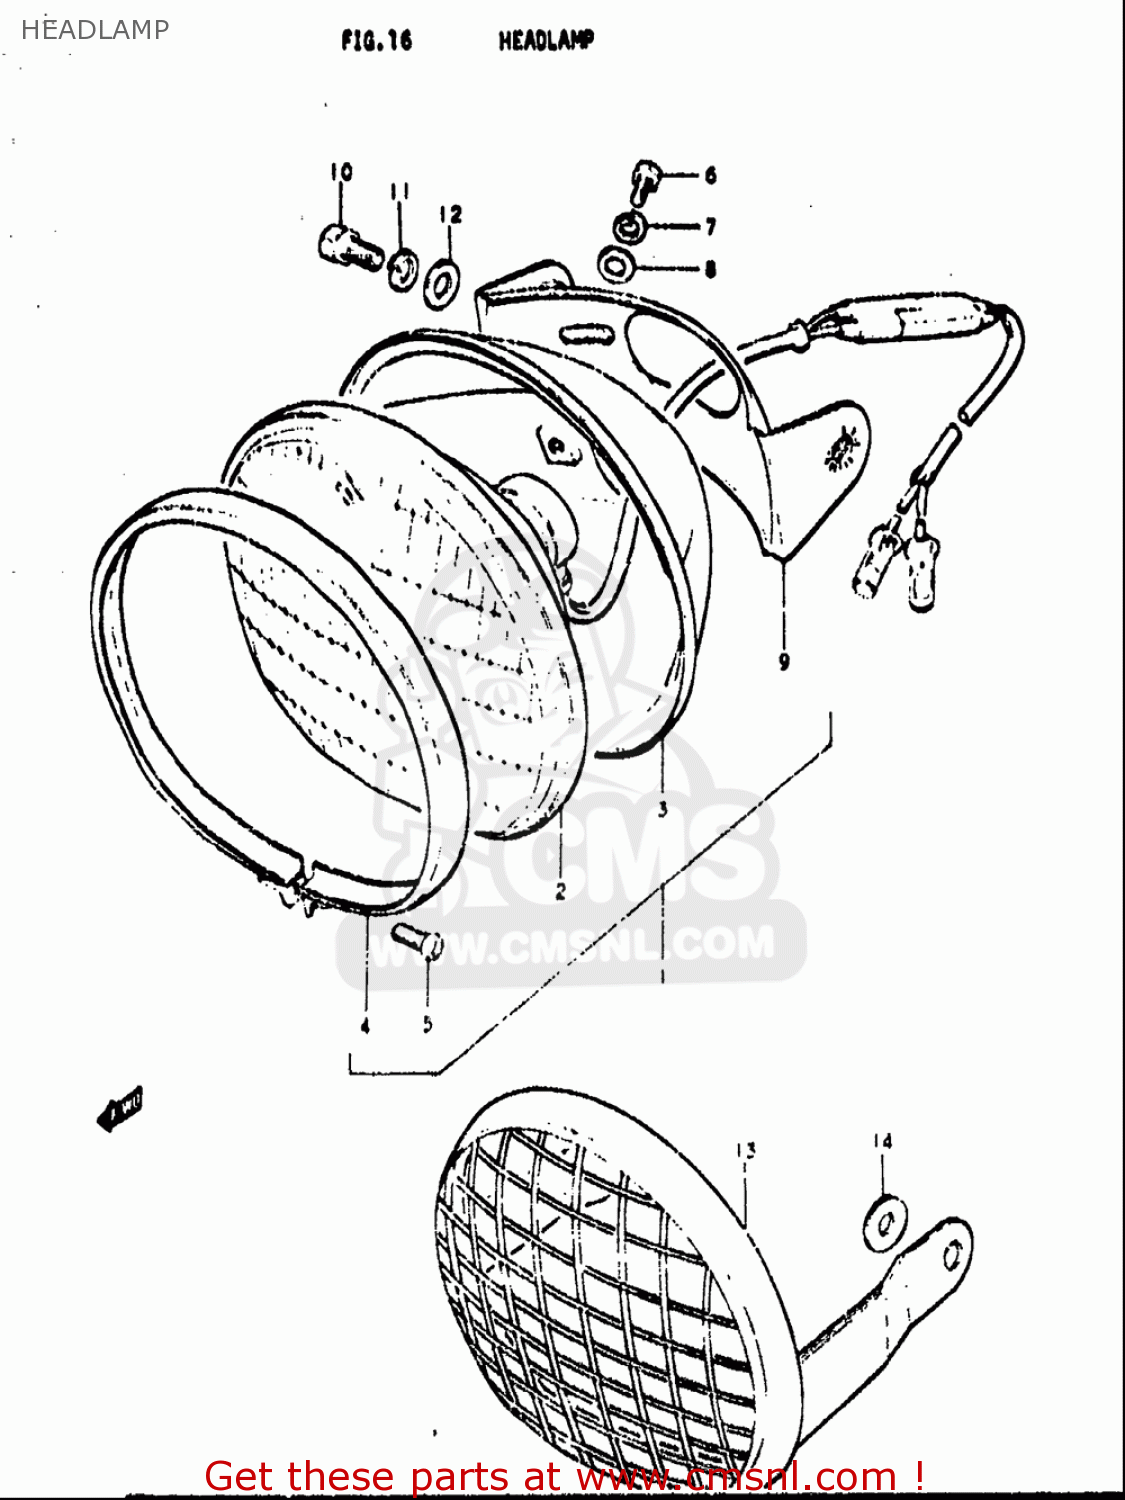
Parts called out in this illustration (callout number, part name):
5	SCREW
6	BOLT
7	WASHER,LOCK
8	WASHER
10	BOLT
11	WASHER,LOCK
12	WASHER
14	WASHER
